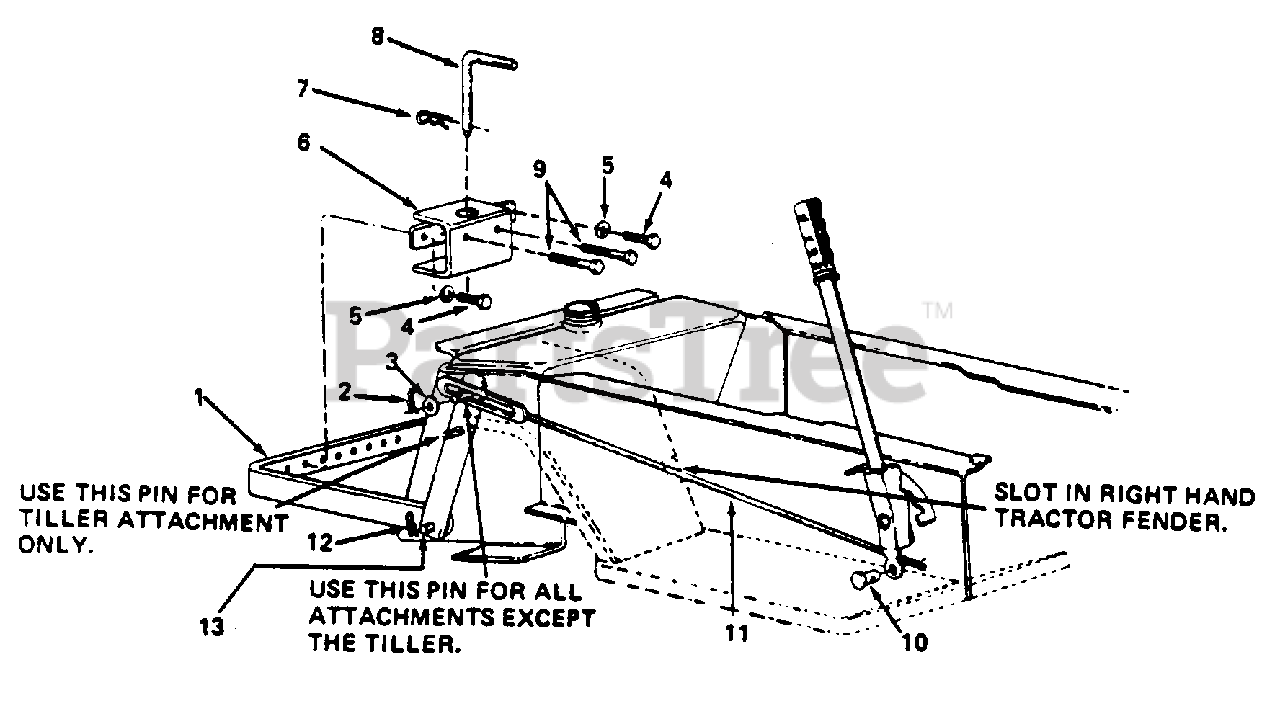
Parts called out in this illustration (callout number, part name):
3	Fl.-Wash. 1/2' I.D.
4	Hex Scr. 1/2-13 x 1.00' Lg.
5	L-Wash. 1/2' Scr.
8	Hitch Pin
9	Hex Scr. 1/2-13 x 3.00' Lg.
10	Adjustrnent Femulle
13	Hitch Rod
